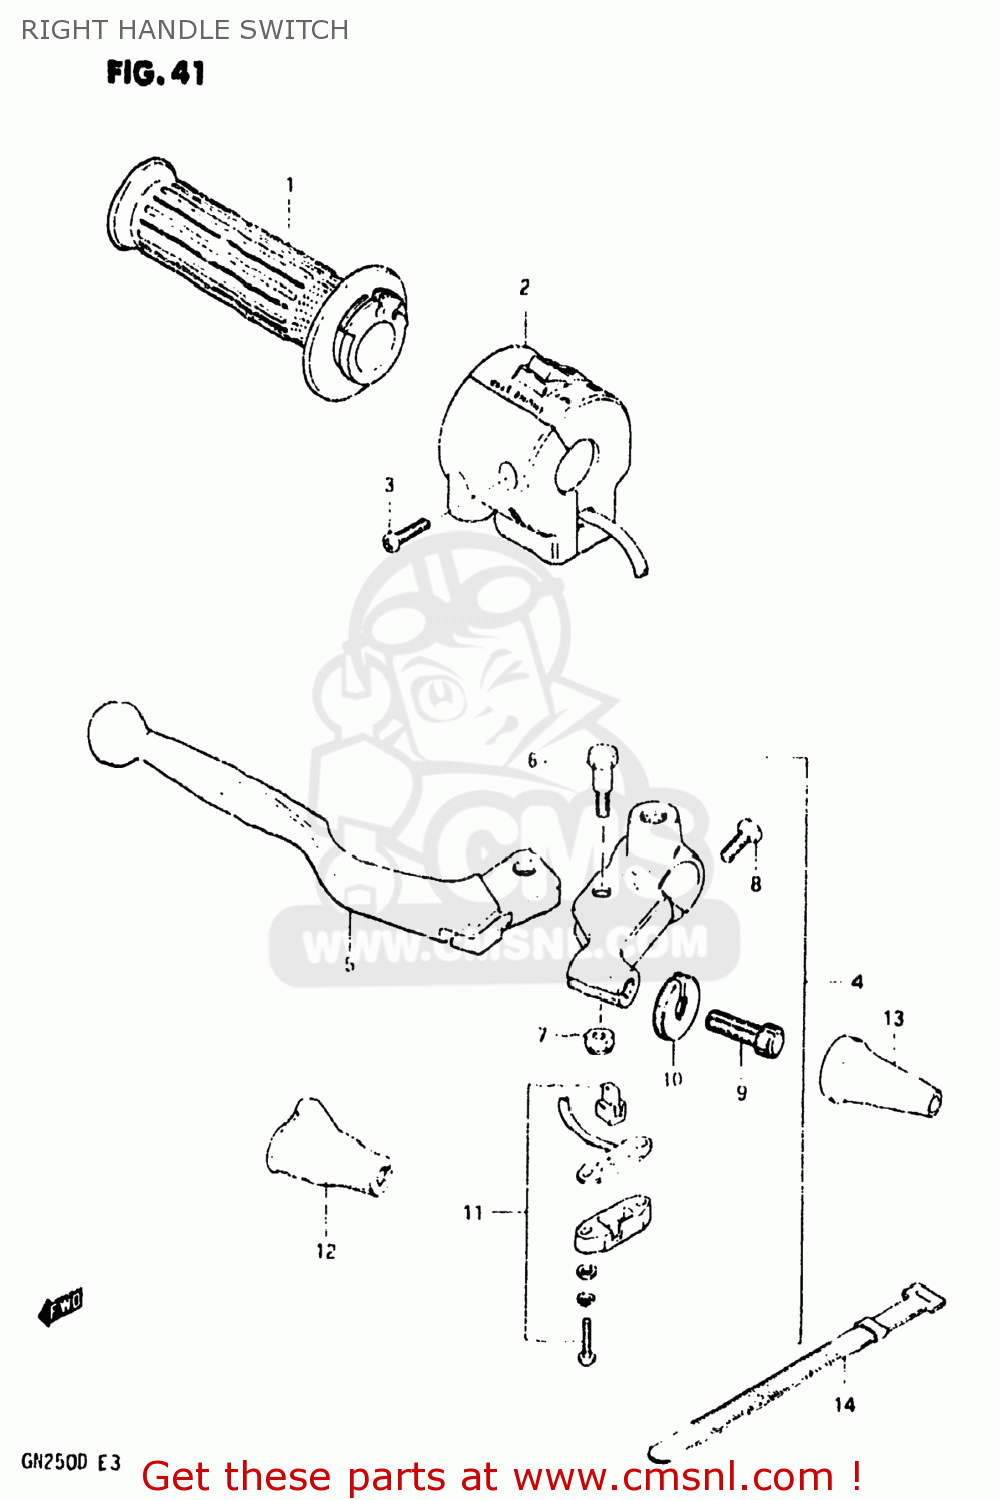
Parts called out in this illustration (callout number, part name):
1	GRIP,THROTTLE
2	SWITCH ASSEMBLY,HANDLE,RIGHT
3	SCREW
4	LEVER ASSEMBLY,BRAKE
5	LEVER,BRAKE
6	BOLT,LEVER
7	NUT 6MM
8	BOLT,CLUTCH LEVER HOLDER
9	ADJUSTER,CABLE
10	NUT,CABLE ADJUSTER LOCK
11	SWITCH ASSEMBLY
12	COVER,BRAKE LEVER DUST
13	BOOT,CLUTCH CABLE
14	CLAMP(L:120)
